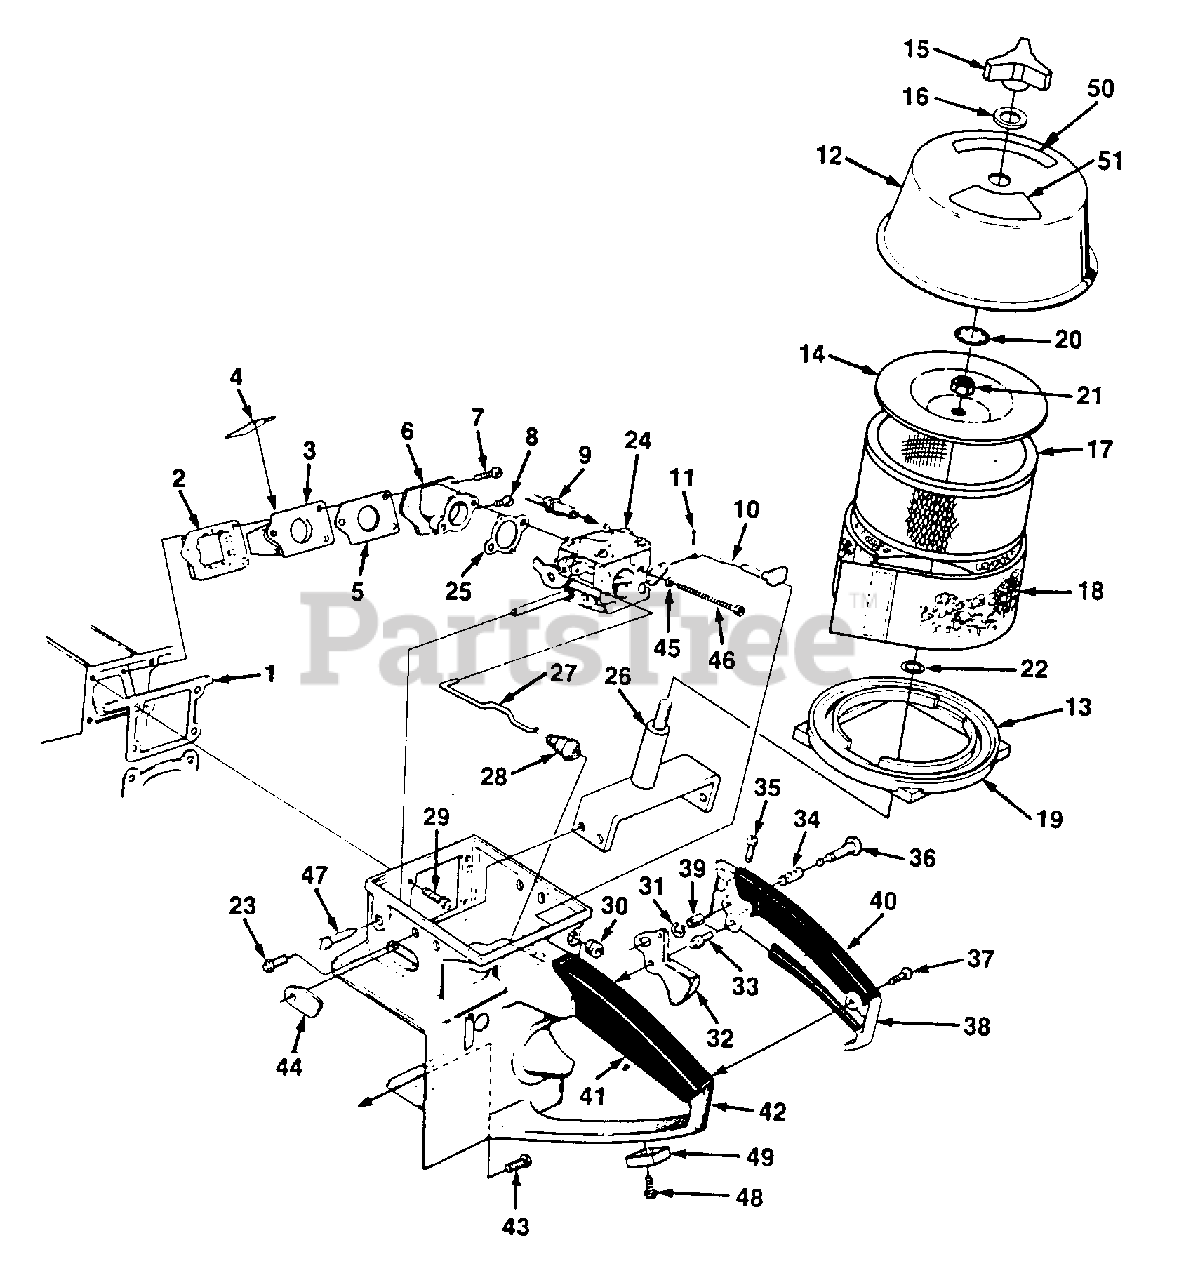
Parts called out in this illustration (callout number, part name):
2	RETAINER-Reed
3	SEAT-Reed valve
4	REED-Valve
6	SPACER-Carburetor
7	SCREW-Pan hd. 8-32 x 1 1/4
8	SCREW-Pan hd. (8-32 x 1")
9	FUEL LINE
10	CHOKE ROD
11	COTTER PIN
12	AIR FILTER COVER
14	COVER-Filter Element
15	KNOB-Cover
17	FILTER ELEMENT-Air
18	PRE FILTER-Felt
19	RING & GASKET ASSEMBLY
20	RING-Retaining
21	NUT-Hex 5/16-18
22	WASHER-Seal
23	SCREW-Pan hd. 8-32 x 1/4
24	CARBURETOR
26	BRACKET-Cover
27	ROD-Throttle
28	BOOT-Throttle rod
29	SCREW-Hex hd. 12-24 x 5/8
30	GROMMET
32	TRIGGER
35	SCREW-8-32 x 5/8
36	PIN-Throttle
37	SCREW-Pan hd. 8-32 x 1/2
38	COVER-Throttle handle
39	BUSHING
40	GRIP-Throttle handle
41	GRIP-Throttle handle
42	HANDLE-Throttle
43	SCREW-Hex hd. 12-24 x 7/8
44	GROMMET
45	WASHER-Lock #10
46	SCREW-10-32 x 1 7/8
47	SCREW-Idle adjustment
48	SCREW-10-24 x 1/2
49	PAD-Wear
50	DECAL-Instruction
51	DECAL-Warning
